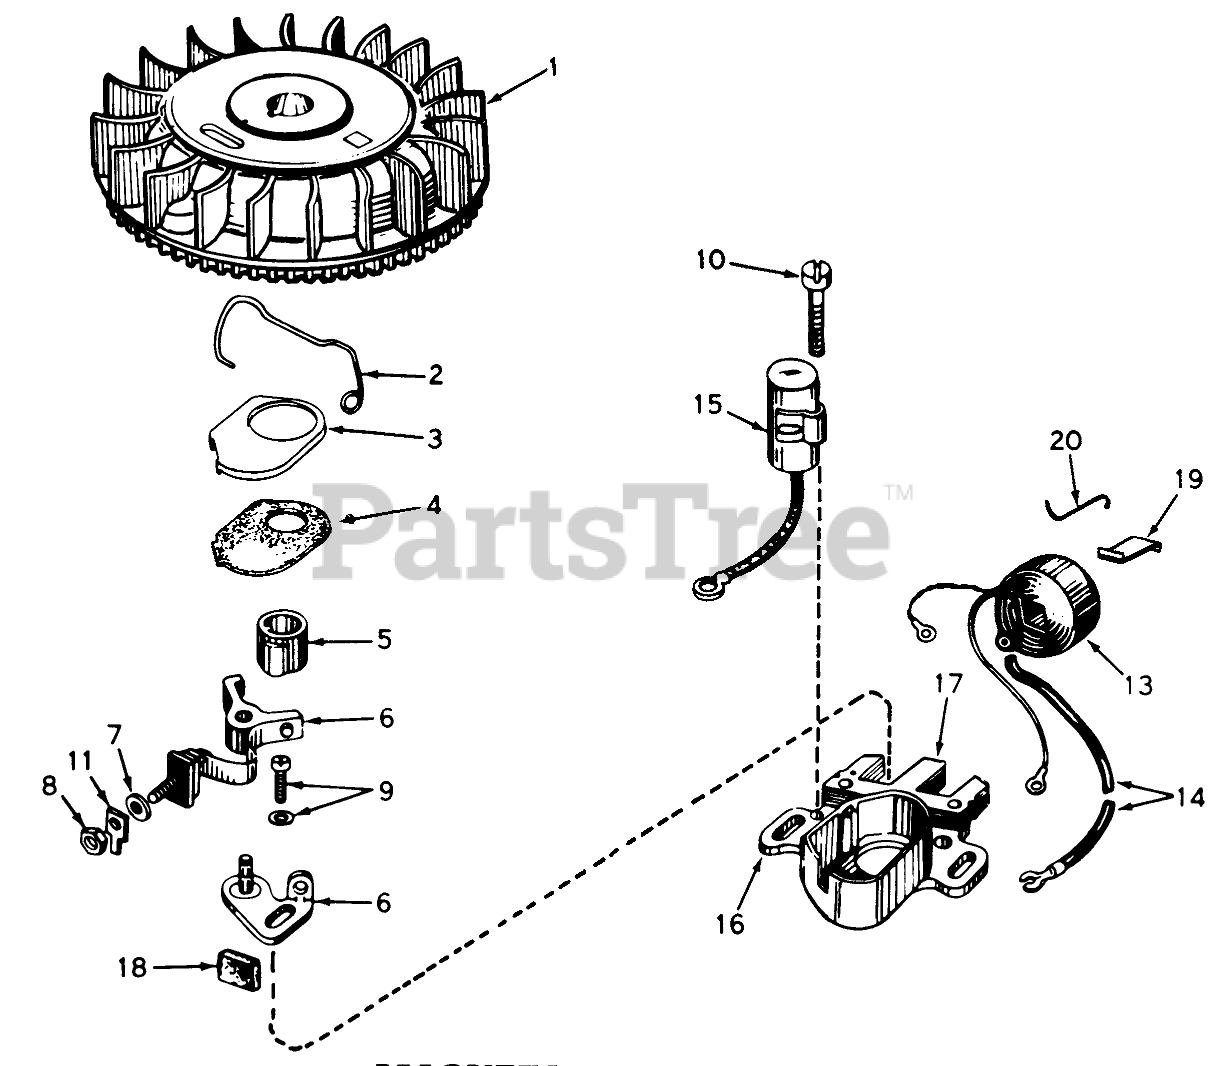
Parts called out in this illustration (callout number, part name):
1	Flywheel
2	Spring Breaker Box
3	Cover-Dust
4	Gasket, Dust Cover
5	Cam, Breaker
6	Breaker Assy.
9	Breaker Screw
10	Condenser Screw
11	Terminal, Ground
13	Coil Assy. (Incl. No. 14)
14	Wire, Lead
15	Condenser
16	Core & Plate
17	Stator Assy. (Incl. Nos. 2, 3, 4, 6 thru 16, 18, 19 & 20)
18	Felt,Cam Wiper
19	Spring Coil Wedge
20	Clip, Coil
